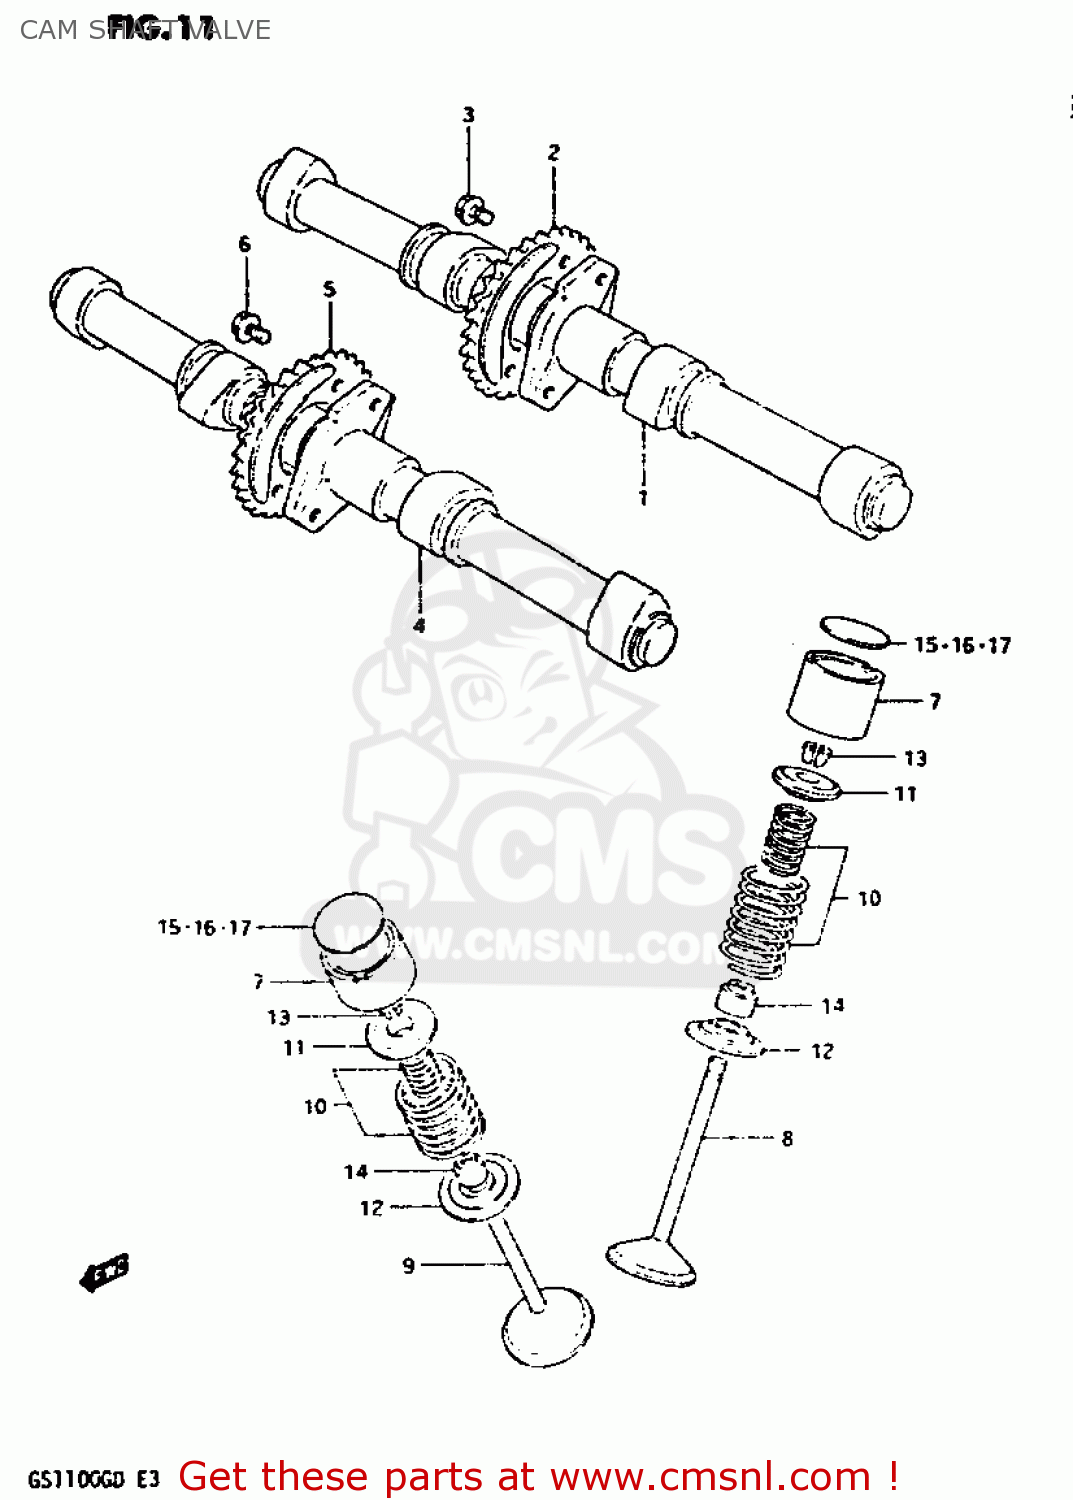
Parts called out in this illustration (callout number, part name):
1	CAMSHAFT,INTAKE
2	SPROCKET,INTAKE CAMSHAFT
3	BOLT(7X11)
4	CAMSHAFT,EXHAUST
5	SPROCKET,EXHAUST CAMSHAFT
6	BOLT(7X11)
7	TAPPET,INTAKE
8	VALVE,INTAKE
9	VALVE,EXHAUST
10	SPRING SET,VALVE
11	RETAINER,VALVE SPRING
12	SEAT,VALVE SPRING
13	COTTER VALVE
14	SEAL,OIL(7X14.4X9)
15	SHIM,TAPPET(T:2.15)
16	SHIM,TAPPET(T:2.60)
17	SHIM,TAPPET(T:3.05)
